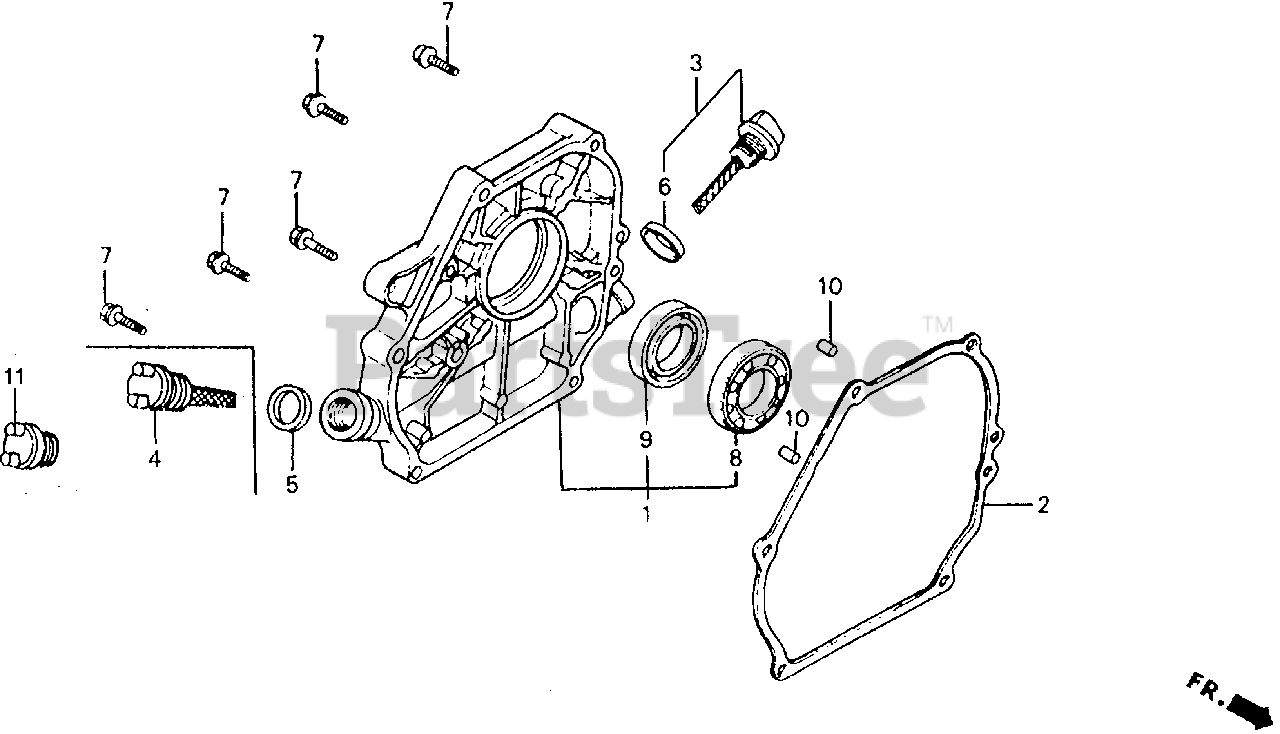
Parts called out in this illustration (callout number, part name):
1	COVER ASSY., CRANKCASE (U-TYPE)
2	GASKET, CASE COVER
3	CAP ASSY., OIL FILLER
4	CAP, OIL HOLE
5	GASKET, OIL FILLER CAP
6	GASKET, OIL FILLER CAP
7	BOLT, FLANGE (6X28)
8	BEARING, RADIAL BALL (62/22)
9	OIL SEAL (22X41X6)
10	PIN A, DOWEL (8X14)
11	CAP, OIL FILLER
